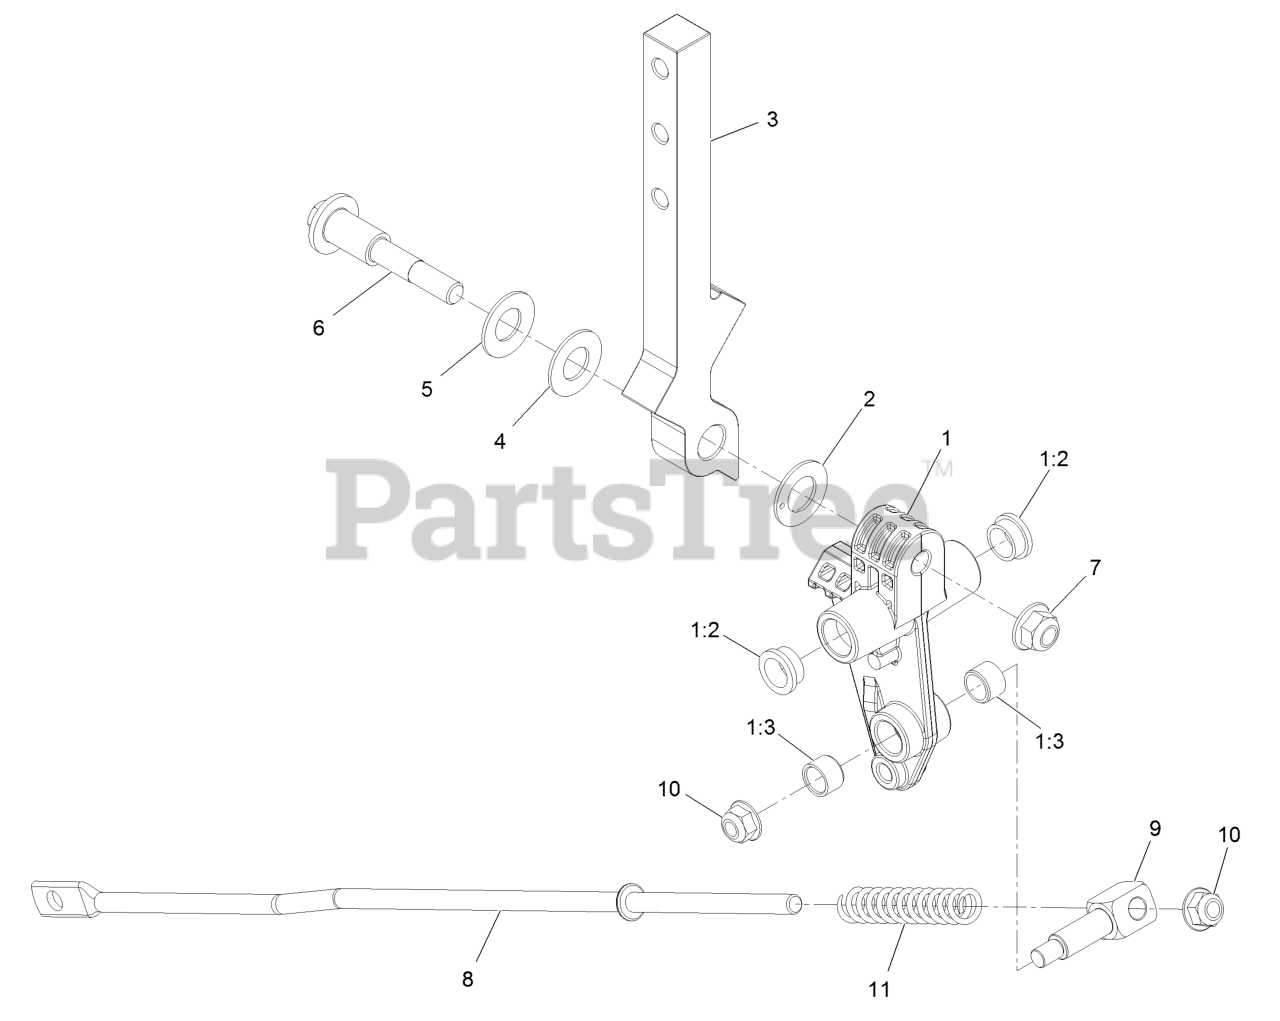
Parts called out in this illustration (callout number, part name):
1	CONTROL ARM ASM
1:2	BUSHING
1:3	BUSHING-SLEEVE
2	WASHER-FRICTION
3	ARM-CONTROL
5	WASHER-BELLEVILLE
6	BOLT-PIVOT
7	NUT-HF, NI
8	LINK-CONTROL
10	NUT-HF, NI
11	SPRING-RETURN, NEUTRAL
